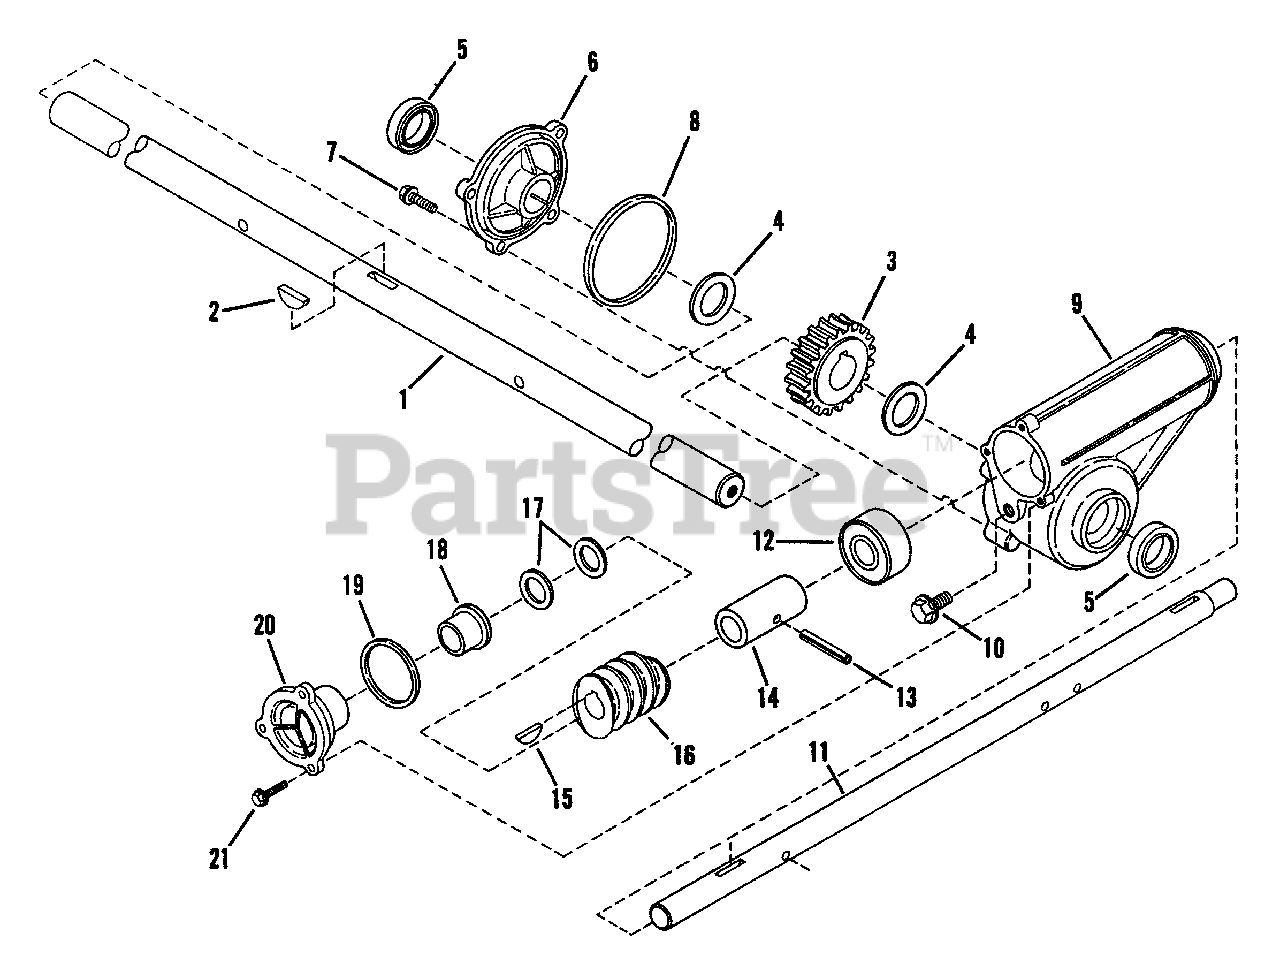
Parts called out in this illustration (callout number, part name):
1	SHAFT, Auger
2	KEY, Woodruff
3	GEAR, Worm
4	WASHER, Thrust
5	SEAL, Oil
6	COVER, Gear Case
7	SCREW, 1/4-20x3/4 Self Tap
8	O-RING (Case Cover)
9	CASE, Gear
10	PLUG, Check (3/8x1/2 Self Tap Screw)
11	SHAFT, Impeller Fan
12	BEARING, Ball
13	PIN, 1/4 x 1-1/2" Roll
15	KEY, 3/16 x 7/8" Woodruff
16	GEAR, Rolled Worm
17	WASHER (Spacers)
18	BUSHING
19	O-RING (End Cap)
20	CAP, End
21	SCREW, 10-24x5/8 Self Tap
